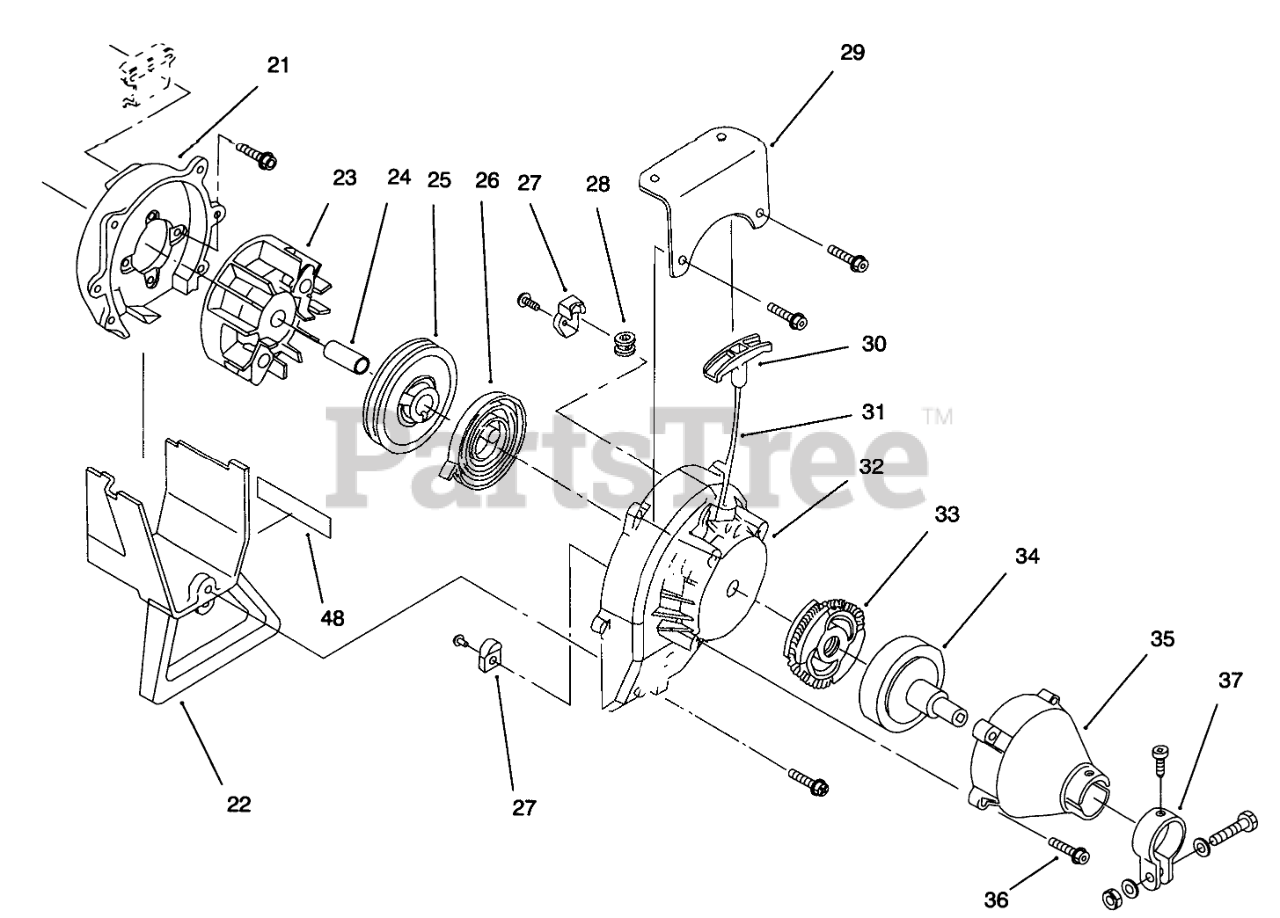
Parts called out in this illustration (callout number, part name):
21	SHROUD ASM
22	Shroud Extension & Stand
23	FLYWHEEL
24	SPACER
25	RECOIL PULLEY ASM
26	RECOIL SPRING
27	PULLEY RETAINER ASM
28	ROPE GUIDE
29	ASM - FUEL TANK GUARD
30	Handle-Pull
32	ASSEMBLY - STARTER HSG
33	Clutch Rotor Asm.
34	CLUTCH DRUM ASM
35	Clutch Cover Asm.
36	CLUTCH COVER SCREW ASM
37	CLAMP ASM - UPPER
48	Decal-Warning
